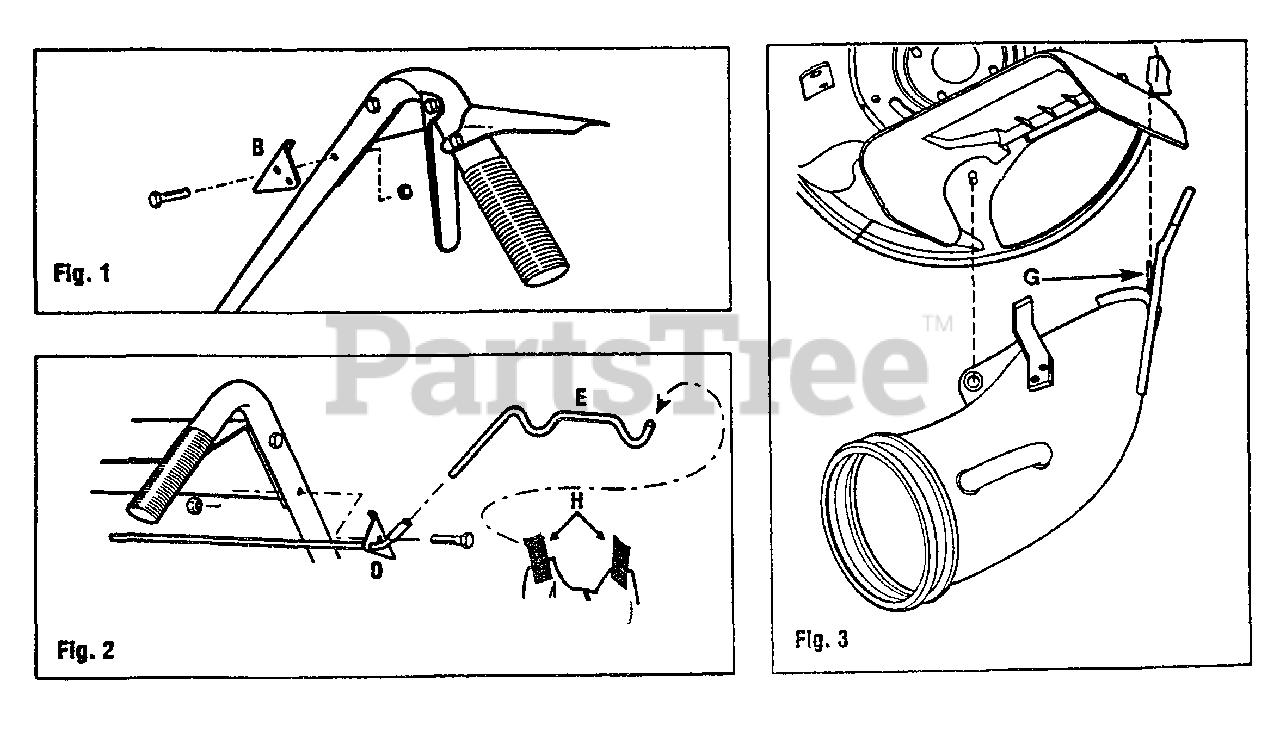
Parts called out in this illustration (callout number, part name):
B	Bracket (Bag Hanger)
G	Chute Assembly
H	Grass Bag Kit
E	Bag Hanger Rod
D	Support Assembly
